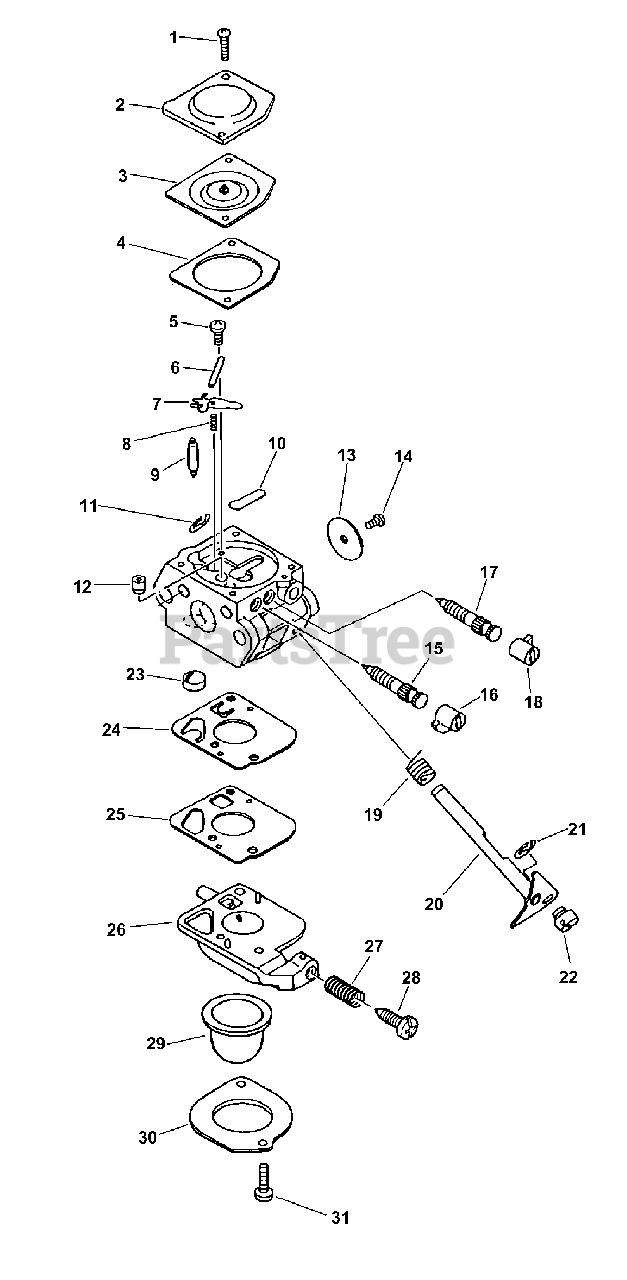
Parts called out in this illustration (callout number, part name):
1	SCREW
2	COVER, METERING DIAPHRAGM
3	DIAPHRAGM, METERING
4	GASKET, METERING
5	SCREW
6	PIN, METERING LEVER
7	LEVER, METERING
8	SPRING, METERING LEVER
9	VALVE, NEEDLE
10	PLUG, WELCH
11	E-RING
12	NOZZLE, CHECK VALVE
13	VALVE, THROTTLE
14	SCREW
15	NEEDLE, HIGH SPEED
16	CAP, LIMITER - RED
17	NEEDLE, LOW SPEED
18	CAP, LIMITER - WHITE
19	SPRING, THROTTLE RETURN
20	SHAFT, THROTTLE
21	CLIP
22	SWIVEL
23	STRAINER
24	DIAPHRAGM, PUMP
25	GASKET, PUMP
26	BODY ASSY, PURGE
27	SPRING
28	SCREW, THROTTLE ADJUST
29	BULB, PURGE
30	RETAINER
31	SCREW
